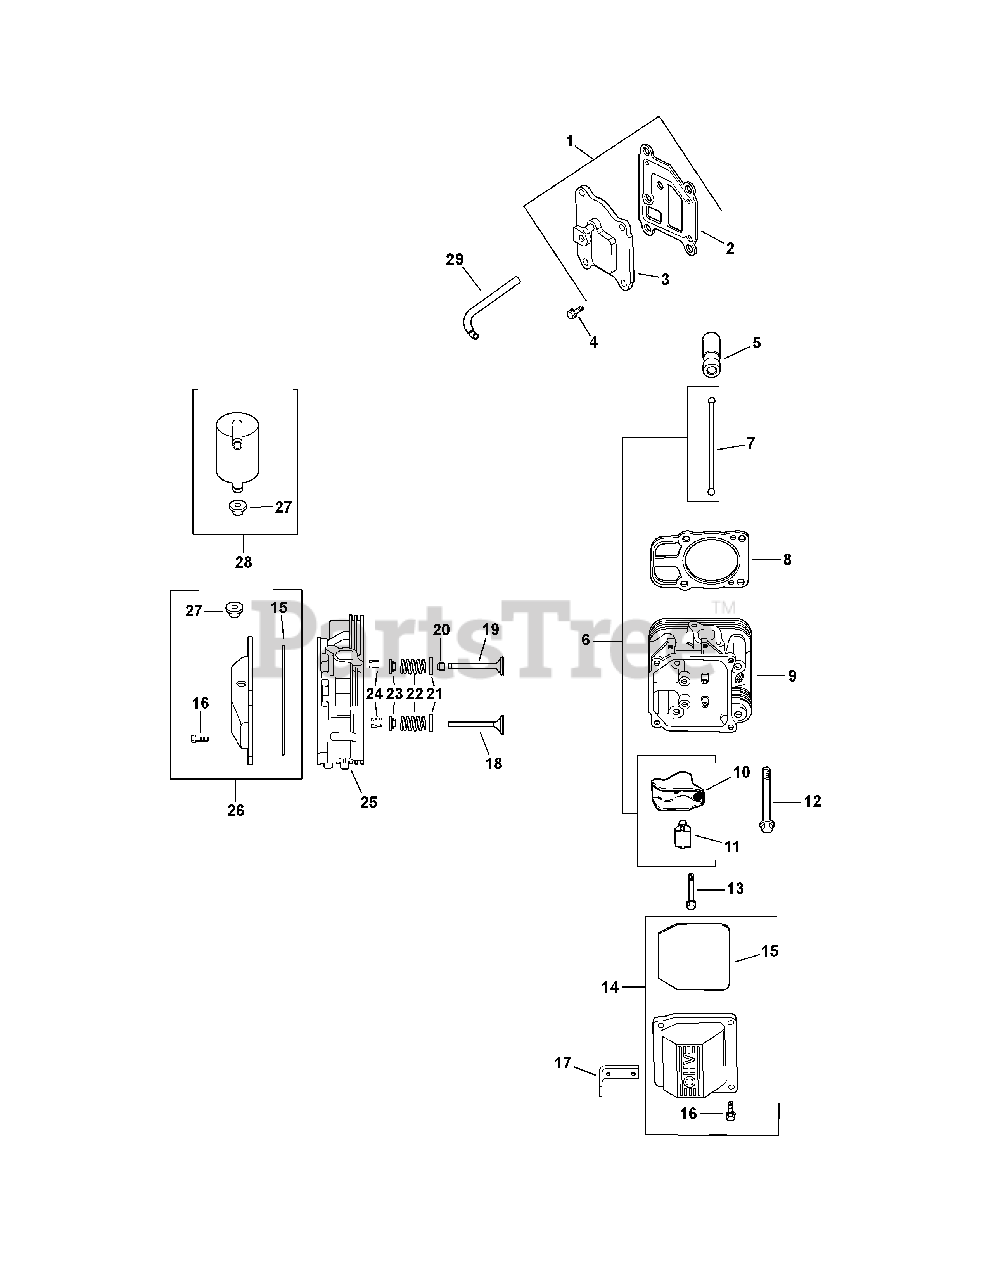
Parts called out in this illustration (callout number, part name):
1	KIT, BREATHER COVER W/GASKET
2	GASKET, BREATHER
3	KIT, BREATHER COVER
4	SCREW, FLG THD FRM M6X1.0X20
5	LIFTER, VALVE HYDRAULIC
6	KIT, VALVE TRAIN
8	KIT, GSKT CYL HD (C22-23 674CC)
9	KIT, CYLINDER HEAD #2
11	PIVOT, ROCKER ARM
12	SCREW,FLG M10X1.5X90
13	SCREW, FLG M6X1.0X34
14	KIT, VALVE COVER-PLAIN
15	O-RING, VALVE COVER
16	SCREW, FLG M6X1.0X30
17	STRAP, LIFTING
18	VALVE, EXHAUST (STD)
18	VALVE, EXHAUST (.25)
19	VALVE, INTAKE (STD)
19	VALVE, INTAKE (.25)
20	SEAL, VALVE STEM
21	RETAINER, SPRING
22	SPRING, VALVE
23	CAP, VALVE SPRING
24	KIT, RETAINER
25	KIT, CYLINDER HEAD #1
26	KIT, VALVE COVER
27	GROMMET, RUBBER
28	KIT, BREATHER SEPARATOR
29	HOSE, BREATHER
